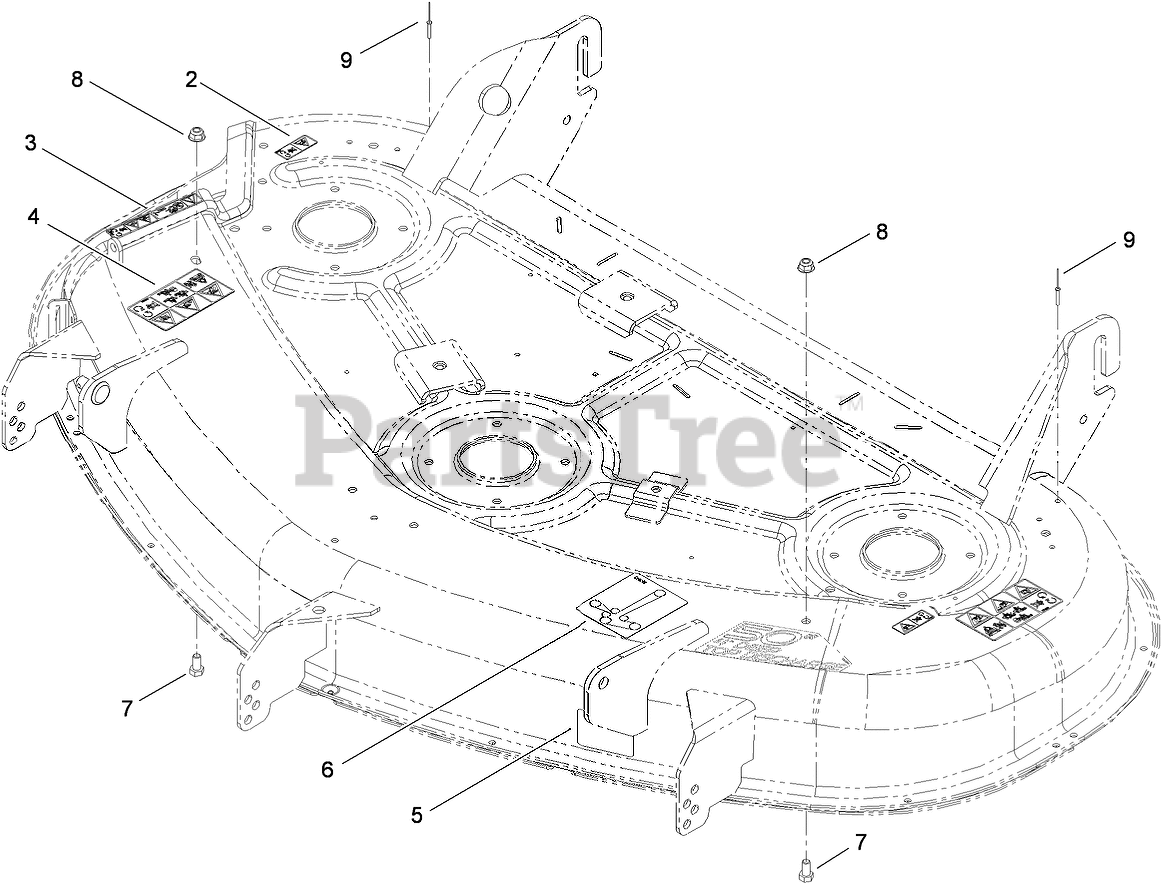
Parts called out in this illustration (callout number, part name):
2	DECAL-DANGER
3	DECAL-DANGER
4	DECAL-DANGER
5	DECAL-SCALP, ANTI
6	DECAL-ROUTING, BELT
7	SCREW-HH
8	NUT-HF, NI
9	RIVET-BLIND
